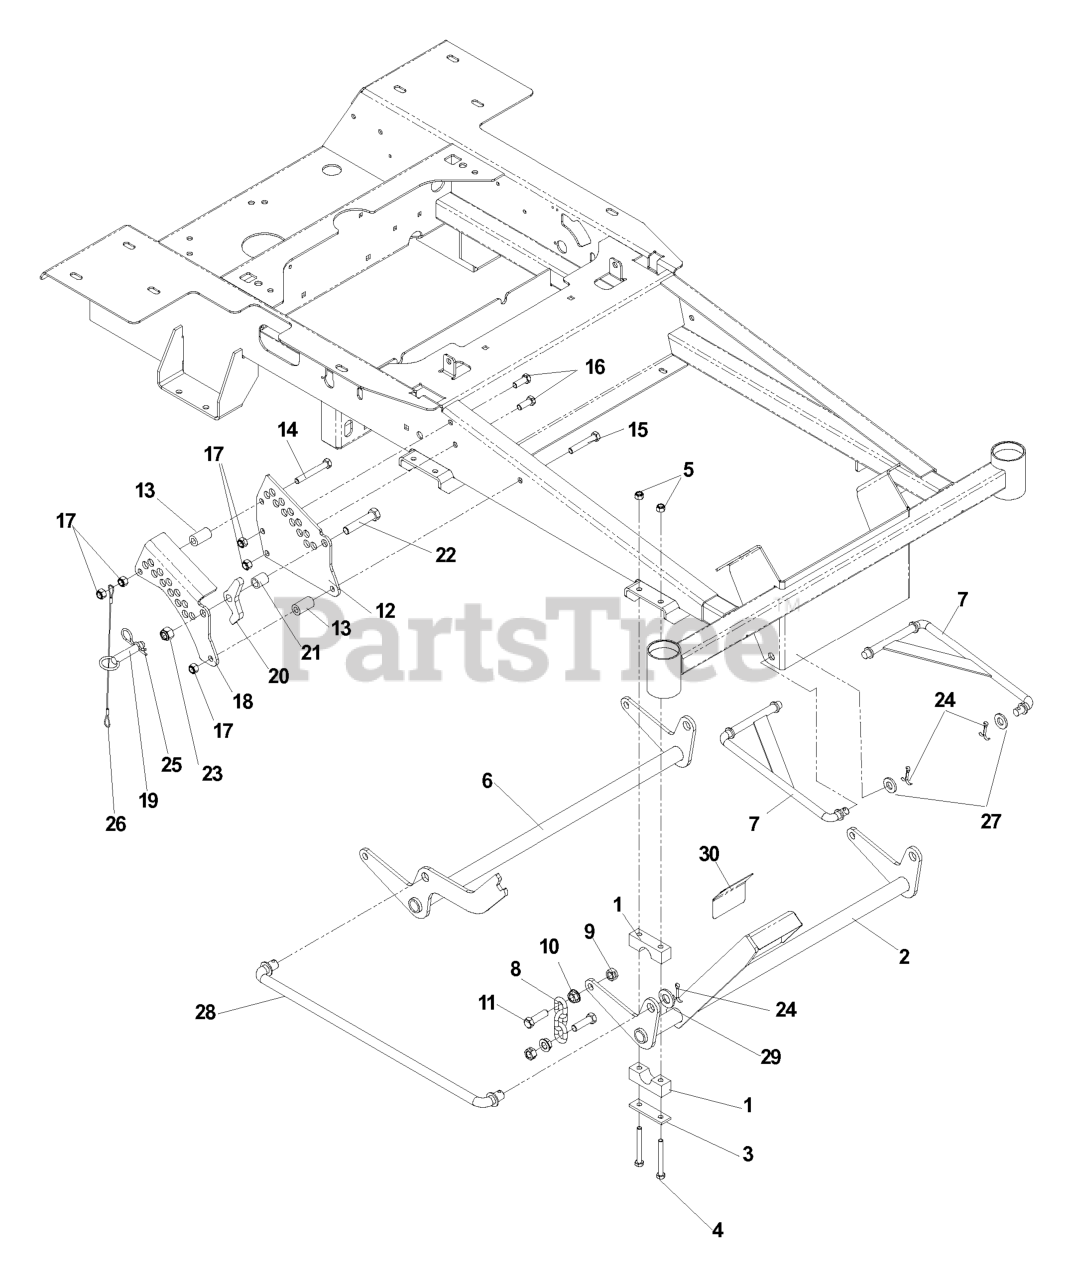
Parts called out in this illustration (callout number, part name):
1	PILLOW BLOCK
2	FRONT LIFT SHAFT
3	REINFORCEMENT BAR
4	HCS 5/16C X 2-3/4
5	NUT 5/16 NYLOC
6	LIFT SHAFT, REAR
7	STRUT LINKAGE
8	LIFT CHAIN - 3 LINK
9	NUT 7/16C CENTERLOCK
10	NUT 7/16C WHIZ
11	HCS 7/16C X 1 1/2
12	HEIGHT ADUST PLATE
13	DECK LIFT SPACER
14	SCREW 3/8C X 2 3/4 HEX CAP
15	HCS 3/8C X 2 1/4
16	HCS 3/8-16X1.GRD.5.ZD
17	NUT 3/8-16 NYLOC
18	HEIGHT ADJUST PLATE, OUTER
20	PAWL, STOP
22	HEX SCREW 1/2-13 X 2.5" GR 5
23	NUT 1/2-13 HEX NYLOC ZD
24	COTTER PIN
25	HAIRPIN #4
27	WASHER 1/2" FLAT
28	CROSS LINK
29	WASHER 5/8 FLAT
30	ANTI-SKID PAD
